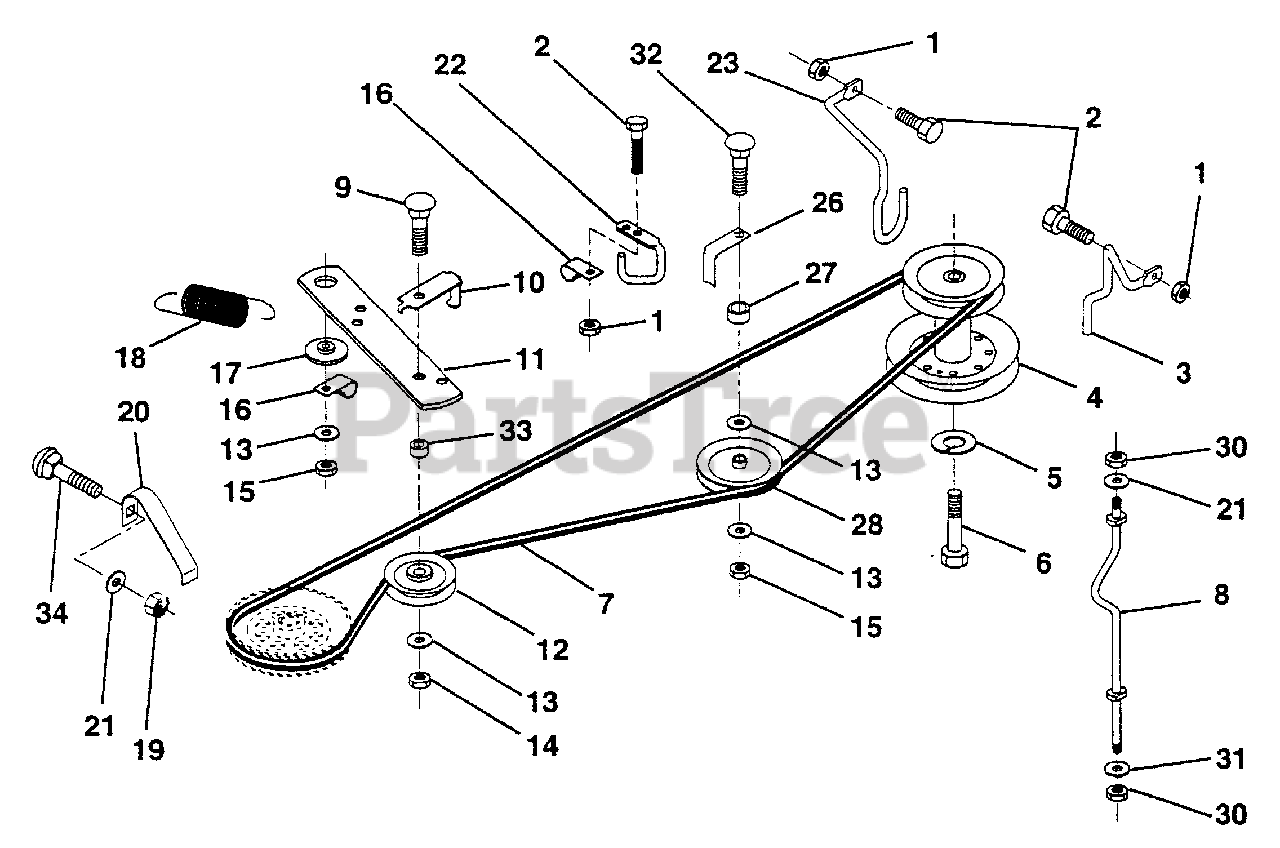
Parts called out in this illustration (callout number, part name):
1	Nut, Lock Hx w/Ins 5/16-18
2	Bolt, Hex Head 5/16-18 x 3/4
3	Keeper, Belt RH Front
4	Pulley, Engine
5	Washer, Lock 7/16
6	Bolt, Hex Fin 7/16-20 Gr. 5
8	Keeper, Belt RH
9	Bolt, RDHD SQ 3/8-16 x 2-1/4
10	Keeper,Belt, Idler Pulley
11	Arm, Idler
12	Idler, Flat
13	Washer 13/32 x 13/16 x 16 Gauge
14	Nut, Centerlock 318-16
15	Nut, Hex, Lock Hex w/wsh 3/8-16
16	Clip Insulator
17	Spacer, Retainer
18	Spring, Extension
20	Keeper,Belt LH
21	Washer Nut Lock Hex w/Ins. 5/6-18
22	Keeper Frame Ground Drive Belt
23	Keeper,Belt LH Front
26	Keeper, Belt
28	Pulley, V-Idler
30	Nut Lock Hex w/Ins. 5/16-18
31	Washer 11/32 x 3/4 x 16 Ga.
32	Carriage Bolt
34	Carriage Bolt
